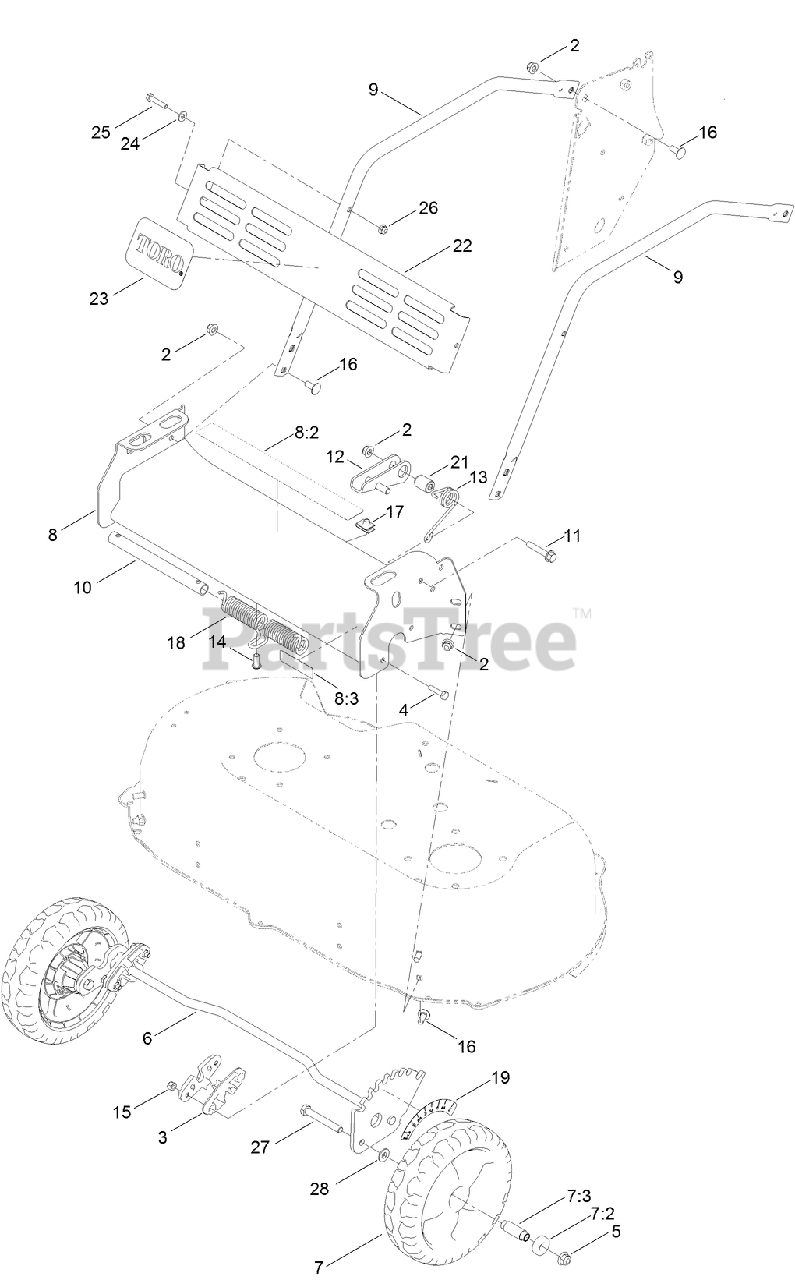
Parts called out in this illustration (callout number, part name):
2	NUT-HF, NI
3	BUSHING-FRONT
4	SCREW-HH
5	NUT-HF, NI
6	AXLE-FRONT
7:2	BEARING-BALL
7:3	SPACER
8	FRONT BUMPER ASM
8:3	DECAL-WARNING
10	MANDRELL-SPRING
11	SCREW-HWH
12	LOCK-HEIGHT, ADJUSTMENT
13	SPRING-TORSION
14	SCREW-HSBH
15	NUT-LOCK, NI
16	SCREW-CARR
17	NUT-U
18	SPRING-TORSION
19	DECAL-HOC, FRONT
21	SPACER
24	WASHER-FLAT
25	SCREW-HH
26	NUT-HF
27	SCREW-HH
28	SPACER-COVER, WHEEL
